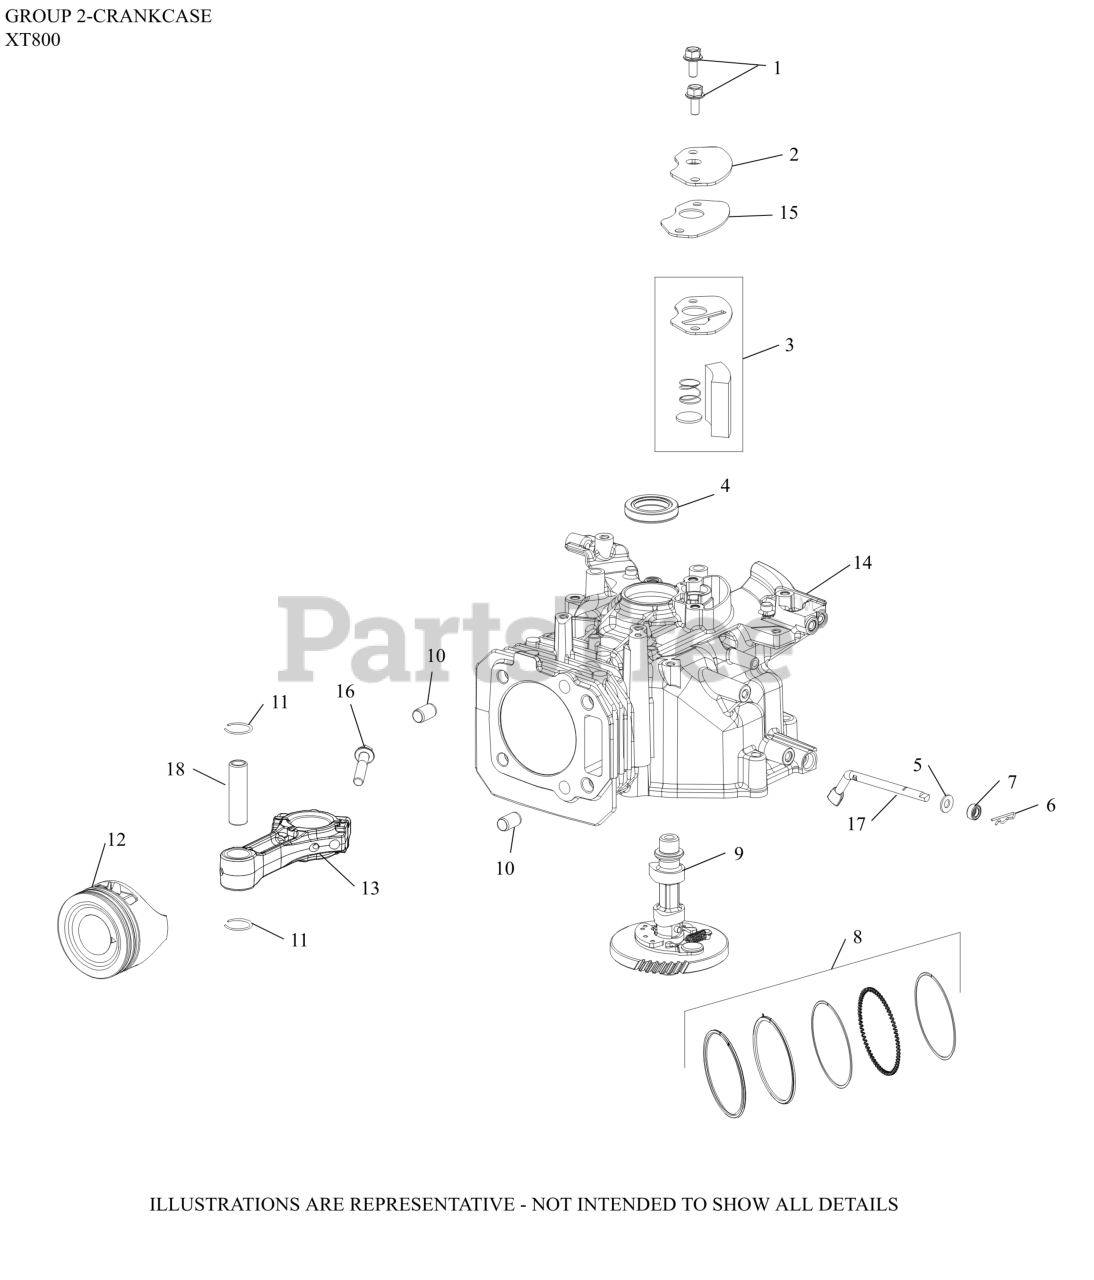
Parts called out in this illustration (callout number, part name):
1	SCREW, HEX FLANGE (M6)-USE 25 086 433-S
2	COVER, BREATHER - (#14096125S)
3	KIT, BREATHER FILTER
4	SEAL, CCASE/FLYWHEEL
5	WASHER, FLAT (DIA 13MM O.D.)-(#1446830S)
6	CLIP, GOVERNOR SHAFT
7	SEAL, OIL
11	RETAINER, PISTON PIN
12	KIT, PISTON
13	CONNECTING ROD
14	CRANKCASE- (#DSC)
16	SCREW, HEX FLANGE (M7)
17	SHAFT, GOVERNOR CROSS
18	PIN, PISTON
